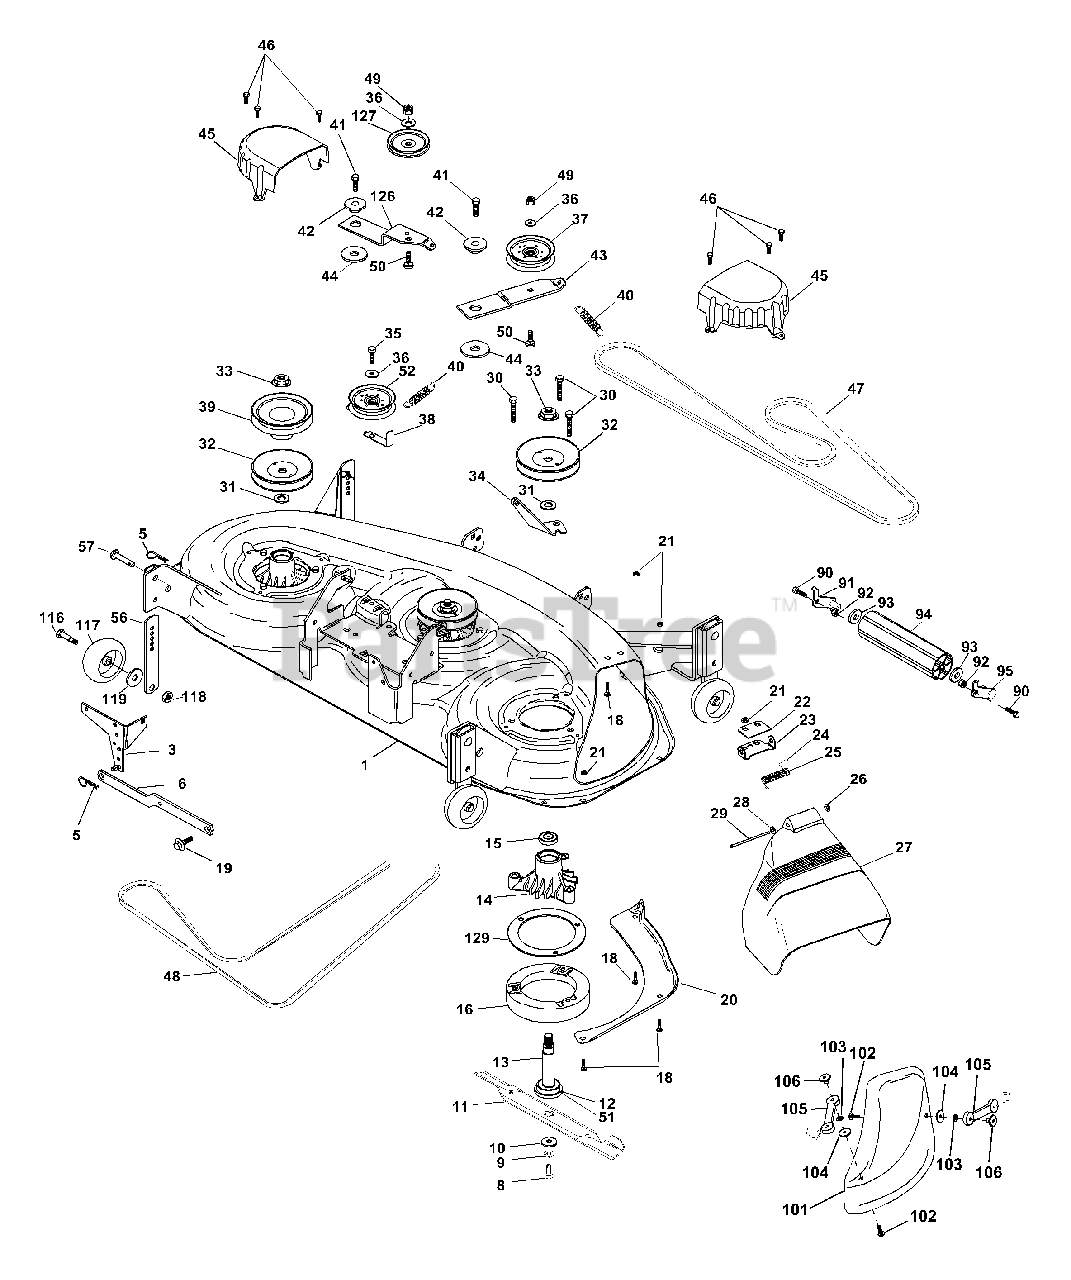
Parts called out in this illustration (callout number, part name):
1	Deck Asm., Mower 46"
3	Bracket Asm., Sway Bar
5	Retainer Spring
6	Arm, Suspension, Rear (Sway Bar)
8	Bolt, Patched 3/8-24 x 1-1/4 Gr. 8
9	Washer, Lock Hvy., Unplated 3/8
10	Washer, Hard Blade, Mower Vented
11	Blade, 46" Mulching
12	Bearing, Ball, Mandrel #6204
13	Shaft Asm. w/Lower Bearing
14	Housing, Mandrel
15	Bearing, Ball, Mandrel
16	Stripper, Mower Round
18	Bolt, Carriage 5/16-18 x 5/8
19	Bolt, Hex Head, Shoulder 5/16-18
20	Baffle, Vortex Mower 46"
21	Nut, Crownlock 5/16-18 UNC
22	Stiffiner, Bracket
23	Bracket, Deflector
24	Cap, Sleeve
25	Spring, Torsion, Deflector
27	Deflector Clipping Shield
28	Washer 11/32 x 5/8 x 16 Ga.
29	Rod, Hinge
30	Screw, Thdroll Washer Hd
31	Washer, Spacer Mower Vented
32	Pulley, Mandrel
33	Nut, Flg. Top Lock Cntr. 9/16
34	Anchor, Spring Deck 46"
35	Screw, Thdroll 3/8-16 x 1-3/4 Tytt
36	Washer 13/32 x 13/16 x 16 Ga.
37	Pulley, Idler, Flat
38	Keeper, Belt, Idler
39	Pulley, Idler, Driven
40	Spring, Secondary 44/46/50 Vent
41	Screw 3/8-16 x 1-1/4
42	Spacer, Retainer Mower
43	Arm, Idler Secondary
44	Washer, Hardened
45	Cover, Mandrel Deck
46	Screw, Thdroll. 1/4-20 x 5/8
47	V-Belt, Mower, Secondary
48	V-Belt, Mower, Primary
49	Nut, Crownlock 3/8-16 UNC
50	Bolt, Carriage 3/8-16 x 1-1/2 Gr. 5
51	Washer Felt
52	Pulley Idler Flat 46 PRI drive
56	Bar Pnt Adjusting Wheel Gauge
57	Pin Head Rivet
90	Bolt Fin Hex 3/8-16 x 1
91	Bracket Asm Noseroller LH
92	Nut Crownlock 3/8-16 UNC
93	Washer 17/32 x 7/8 x 16 Ga.
94	Roller Nose
95	Bracket Asm Noseroller RH
101	Cover, Mulching
102	Screw
103	Washer, Lock #10
105	Latch Asm. Mulch/Bagger
106	Nut, Weld
116	Bolt, Shoulder
117	Gauge Wheel, Wide
118	Nut, Centerlock 3/8-16 UNC
119	Washer 3/8 x 7/8 x 14 Ga.
126	Arm, Idler, Primary Deck 46"
127	Pulley, Idler, V-Groove Dim. 4.25
129	Reinforcement Mandrel Ring
129	Mandrel Asm 44"/50" Service
